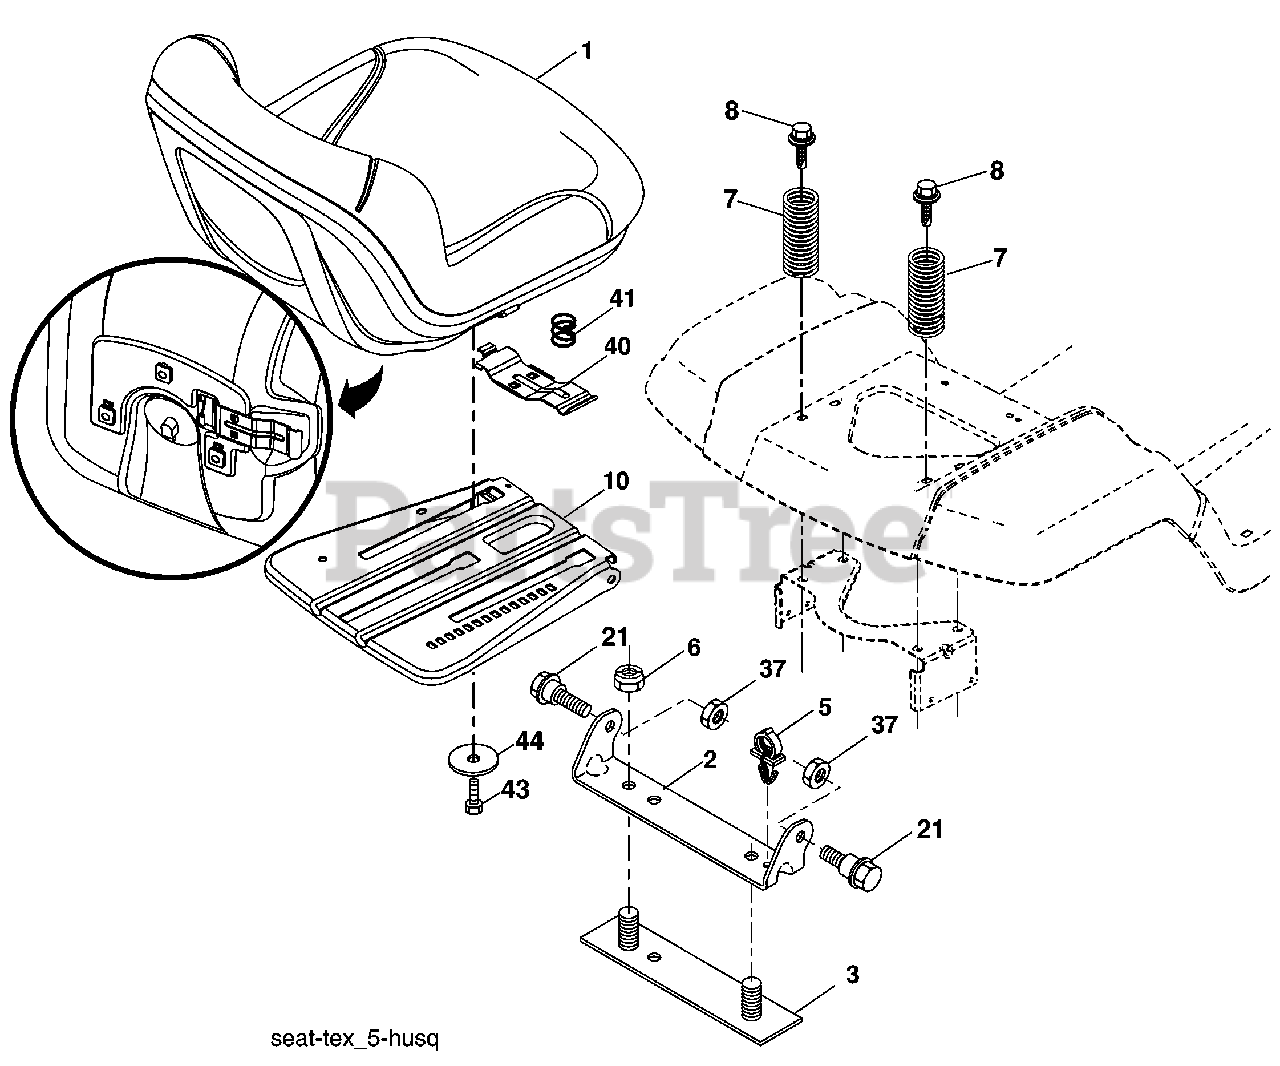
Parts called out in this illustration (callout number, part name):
1	Seat
2	Bracket Pivot Fender
3	Strap, Asm Fender
5	Clip, Push In, Hinged
6	Nut, Lock W/Ins. 3/8-16 unc
7	Spring, Seat Cprsn
8	Bolt 5/16-18 uncx 3/4 w/Sems
10	Pan, Seat
21	Bolt, Shoulder 5/16-18
37	Nut, Lock 5/16-18 unc
40	Handle Slide Seat
41	Spring Latch Seat
43	Bolt 3/8-16 x 3/4
44	Washer 13/32 x 2-3/8 x 12
